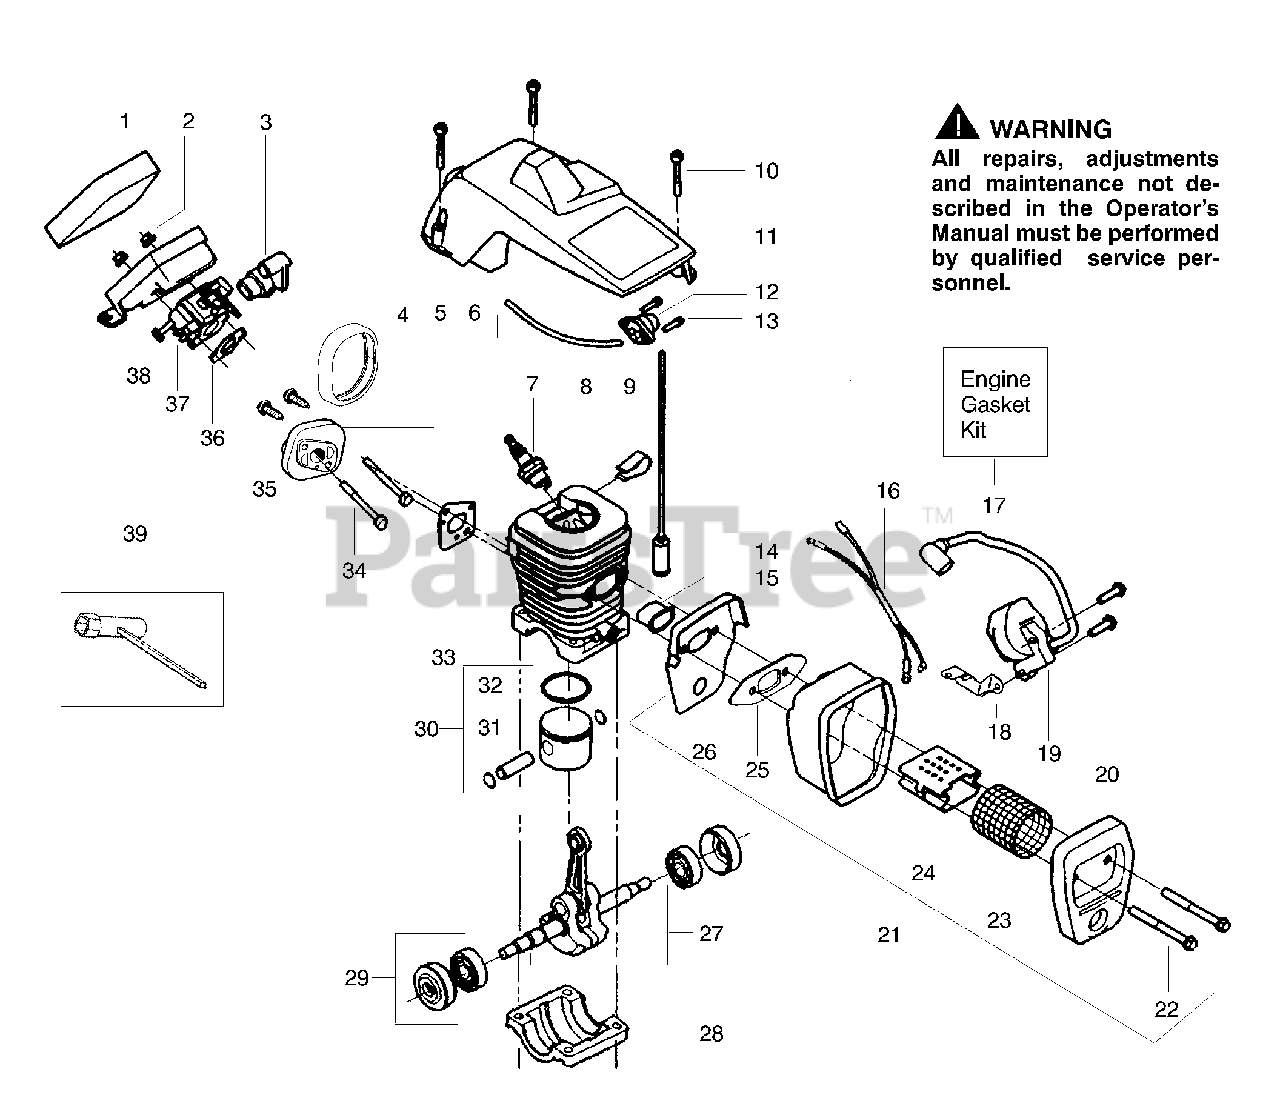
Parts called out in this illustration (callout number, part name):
1	Foam Air Filter
3	Grommet Carb Adjust
4	Seal Carb Adapter
5	Adapter Carb.
6	Kit Fuel Line (Small)
7	Spark Plug (RCJ 7Y)
8	Kit Cylinder
9	Clip High Tension Lead
11	Shield Cylinder
12	Assy Air Purge
14	Assy Fuel Pick up
15	Insulator Heat
16	Assy. Wire Harness
17	Kit Engine Gasket
18	Strap Ground
19	Module Ignition
21	Assy Muffler
23	Screen Spark
24	Diffuser Muffler
25	Gasket Muffler(kit)
26	Backplate Muffler
27	Assy. Crankshaft
28	Cap Crankcase
29	Assy. Seal & Bearing
30	Kit Piston
31	Retainer Piston Pin
32	Ring Piston
33	Gasket Adapter (kit)
36	Gasket Carb. (kit)
37	Kit Carburetor (WT324)
38	Housing Air Filter
39	Wrench Bar
